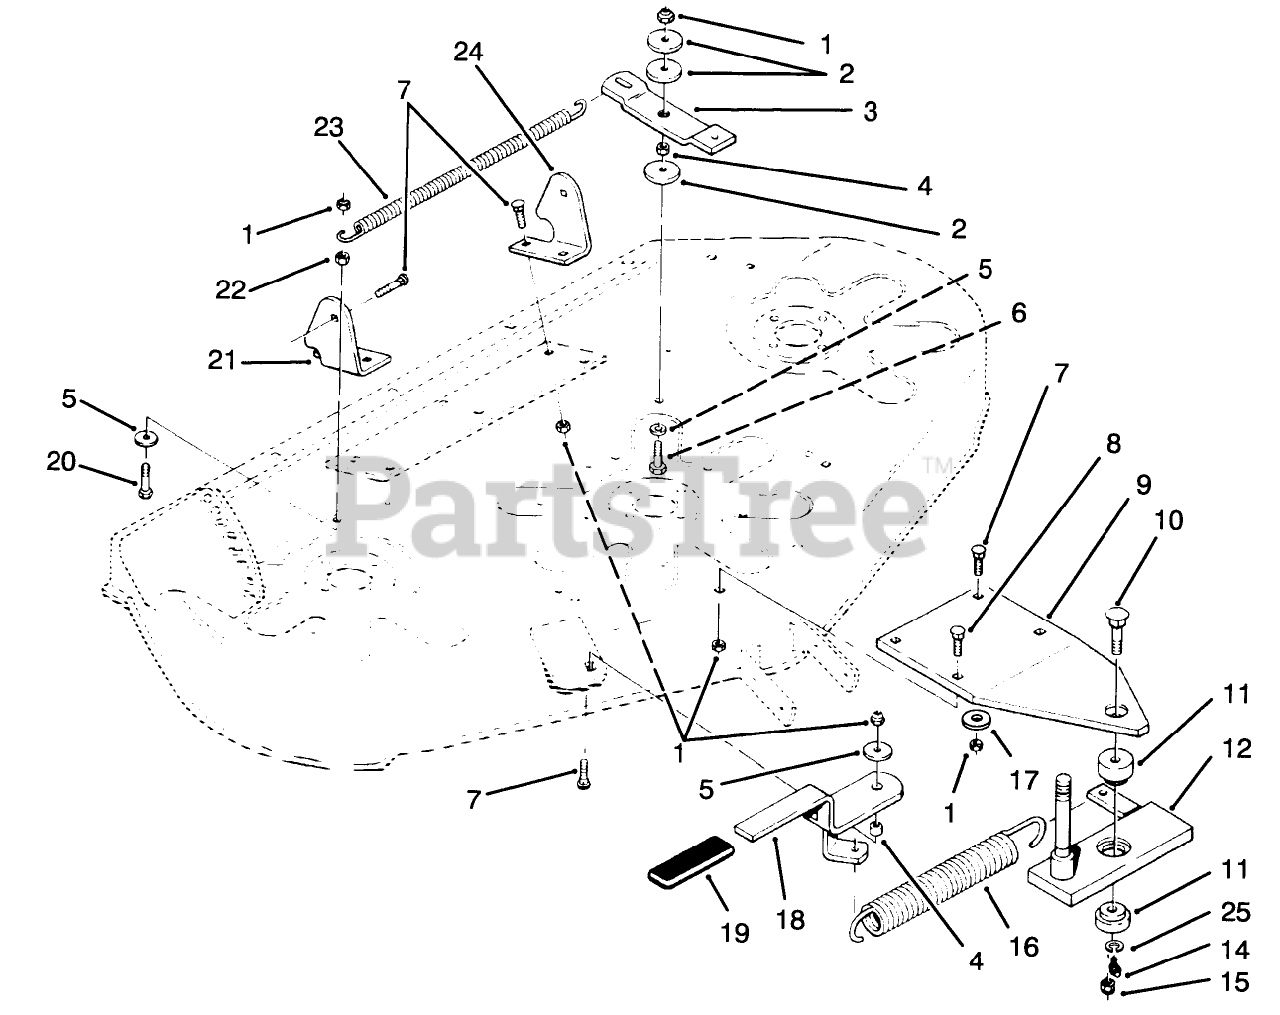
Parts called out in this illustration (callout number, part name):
1	NUT-LOCK, NI
2	WASHER
3	Arm-Idler
4	SPACER
5	WASHER
6	SCREW-HH
7	BOLT-CARR
8	BOLT-CARR
9	Plate
10	SCREW-CARR
11	BUSHING
12	Countershaft
14	FITTING GREASE
15	NUT-LOCK, NI
16	Spring
17	WASHER-SPACER
18	Lever
20	SCREW-HH
21	Bracket RH
22	NUT-HEX
23	SPRING - EXTENSION
24	Bracket LH
25	WASHER-LOCK
